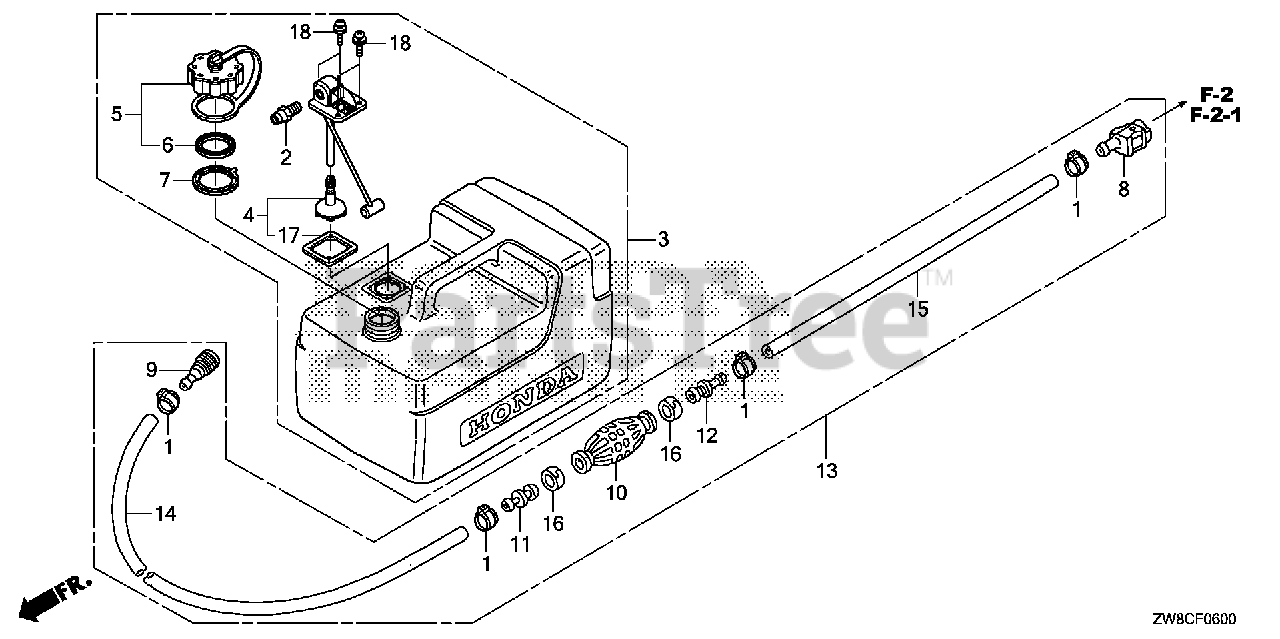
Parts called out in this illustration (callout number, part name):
1	CLAMP, FUEL TUBE (14.0)
2	FITTING, QUICK DISCONNECT
3	TANK ASSY., FUEL
4	FILTER KIT, FUEL
6	GASKET, FUEL CAP
7	RETAINER, PRESSURE RELIEF
8	CONNECTOR ASSY., FUEL (A)
9	CONNECTOR, FUEL
10	BULB, PRIMER
11	VALVE, IN.
12	VALVE, OUTLET
13	TUBE ASSY., FUEL TANK
14	TUBE, FUEL LONG (7.3X2000)
15	TUBE, FUEL SHORT
16	BAND, TUBE CLIP (20MM)
17	GASKET, FUEL PICK-UP
18	BOLT-WASHER (5MM) (SEAL)
